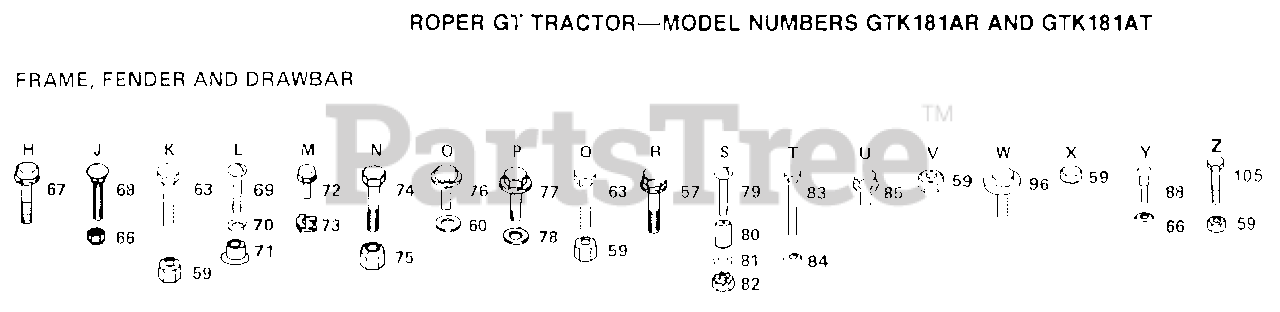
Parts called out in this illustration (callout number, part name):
57	SCREW
60	WASHER PM
63	BOLT
68	BOLT
69	SCREW
70	LOCKWASHER
71	WELDNUT
73	"""J"" FASTENER LT"
74	BOLT T
77	SCREW
78	No Desciption for Part
79	SCREW
80	SPACER LT
81	WASHER
83	BOLT
84	NUT GTV
85	SCREW LT
96	SCREW LT
